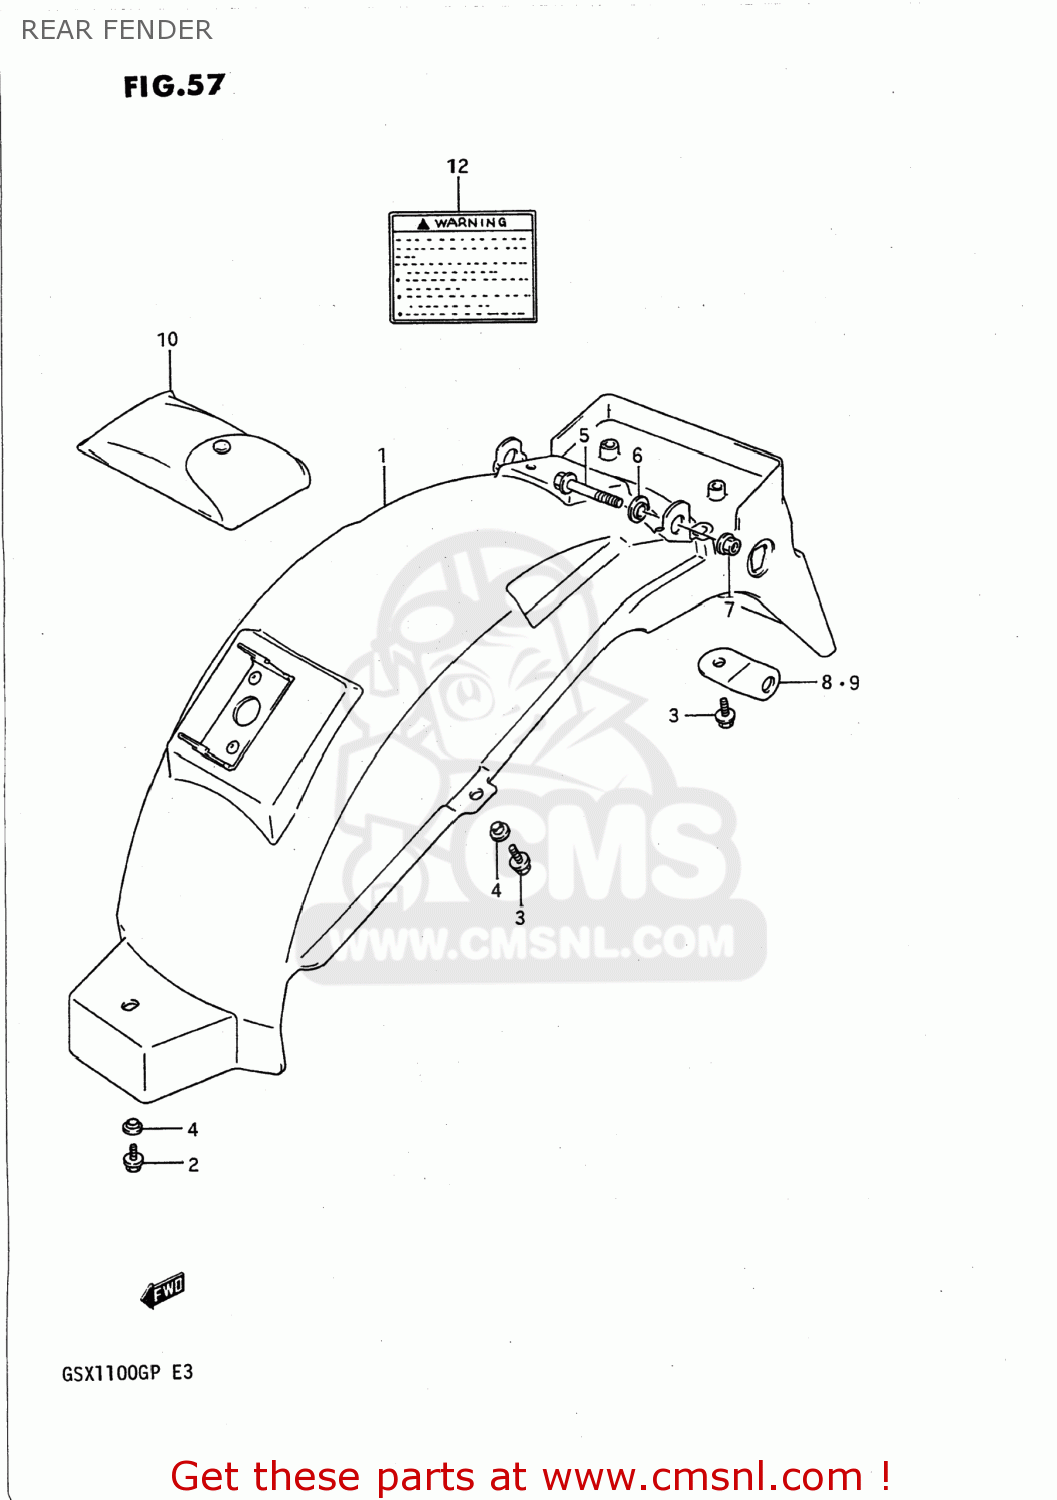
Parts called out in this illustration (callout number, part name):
1	FENDER,REAR
2	BOLT
3	BOLT 6X16
4	WASHER
5	BOLT 8X55
6	WASHER
7	NUT
8	REINFORCEMENT,REAR TURN SIGNAL
9	REINFORCEMENT,REAR TURN SIGNAL
10	TOOL ASSY
12	LABEL
13	LABEL (TIRE AIR PRESSURE)
